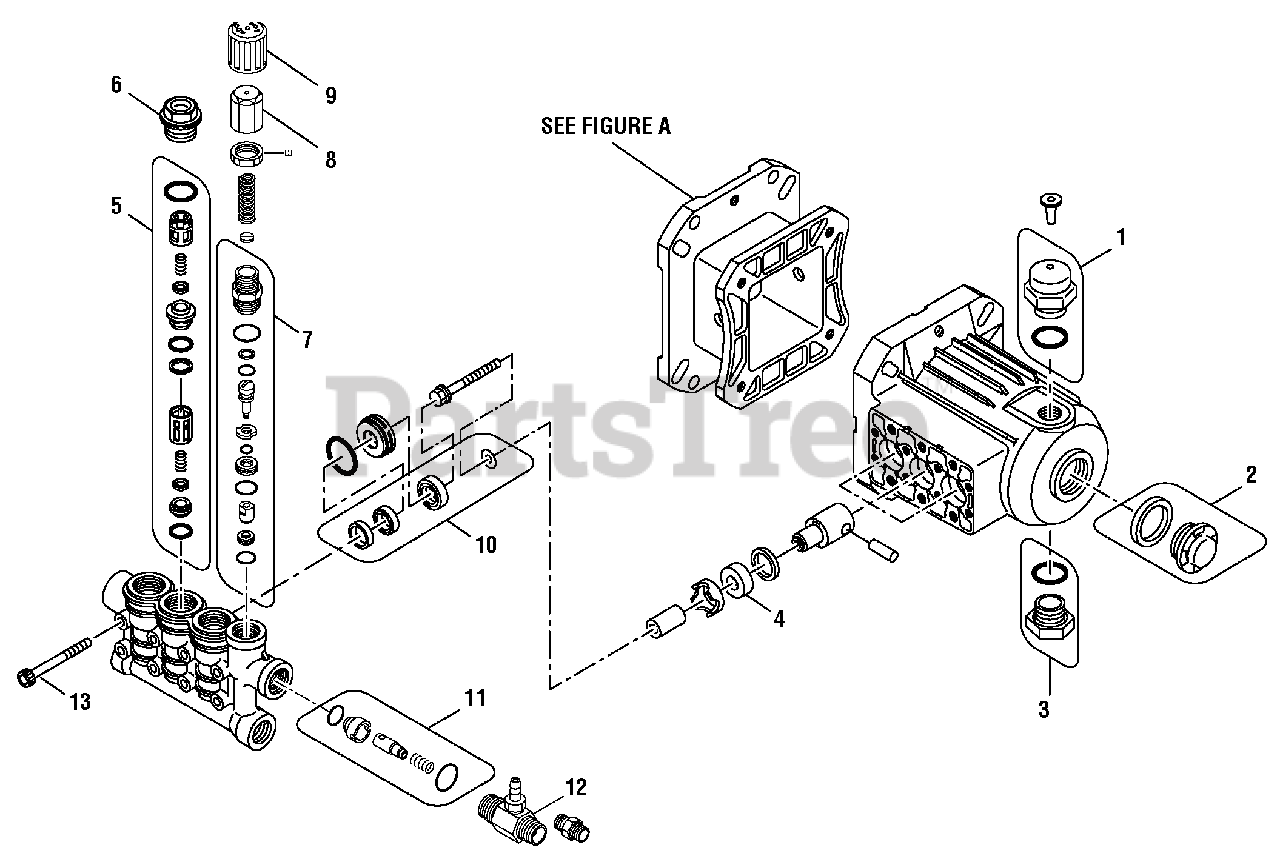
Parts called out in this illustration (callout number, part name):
1	Vent Plug w/O-Ring
2	Sight Glass w/Gasket
3	Drain Plug w/O-Ring
5	Valve and Seal Kit
6	Valve Plug
7	Unloader Kit
8	Adjustment Cap
9	Adjustment Handle
10	Piston Seal Kit
11	Chemical Injector Kit
12	Chemical Injector
13	Manifold Bolt
